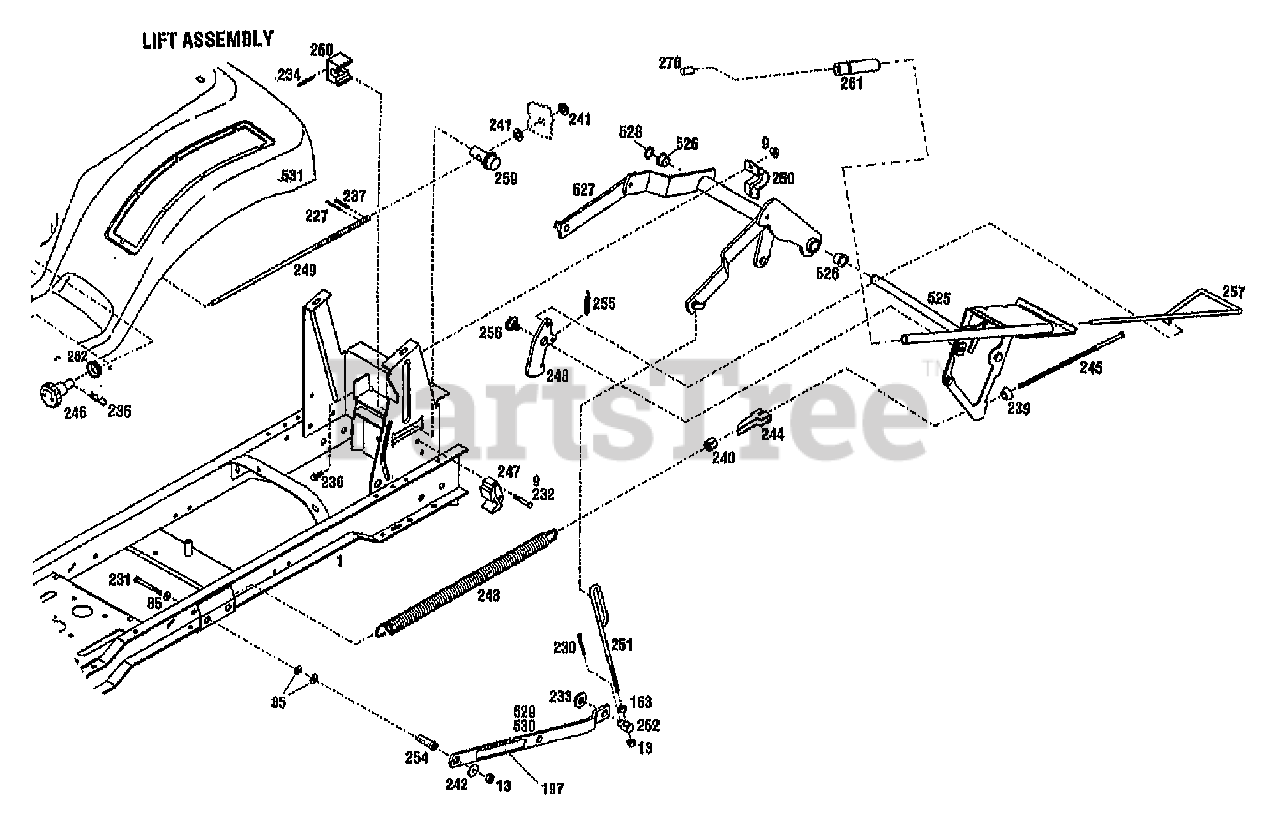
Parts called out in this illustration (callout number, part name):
9	NUT-HFLK 5/16-18 ZP
13	NUT-LOCK 3/8-16
85	WASHER-FLAT 3/8 SAE
163	NUT-HEX 3/8-16 ZP
197	DECAL-WARNING
227	PIN-COTTER .125 X .75 ZP
230	PIN-COTTER .120X1.25 ZP
231	SCR-HH 3/8-16X3.0 G5 ZP
232	SCR-HH 5/16-18X1.5 G5 ZP
233	WASHER-1.305X.649X.098 ZP
234	PIN-DRIVE
235	PIN-HITCH
236	SCR-HFLK 5/16-18X.75 ZP
237	PIN-ROLL .156X1.0
239	BEARING-SPHERICAL
240	NUT-SPECIAL 5/16-18
242	WASHER-1.5X.375X.18 ZP
243	SPRING-LIFT ASSIST
244	BRKT-LIFT ASSIST
245	SCR-LIFT ASSIST
246	KNOB-HEIGHT ADJUST
247	BLOCK-DETENT
249	KIT-SVC SCR HGT ADJ
250	CLAMP-LIFT
251	ROD-LIFT
252	SWIVEL-LIFT REAR
254	SPACER
255	SPRING-EXTENSION
256	SCR-SHOULDER
259	BLOCK-HEIGHT ADJUST
260	COLLAR-HEIGHT ADJUST
261	GRIP-LIFT
262	GROMMET-SNAP BUSHING
276	BUTTON-LIFT
525	HANDLE-LIFT
528	RING-RETAINING EXT .694 ID
529	LINK-LIFT W/DECAL
530	LINK-LIFT W/DECAL
531	FENDER-RED W/DECALS
